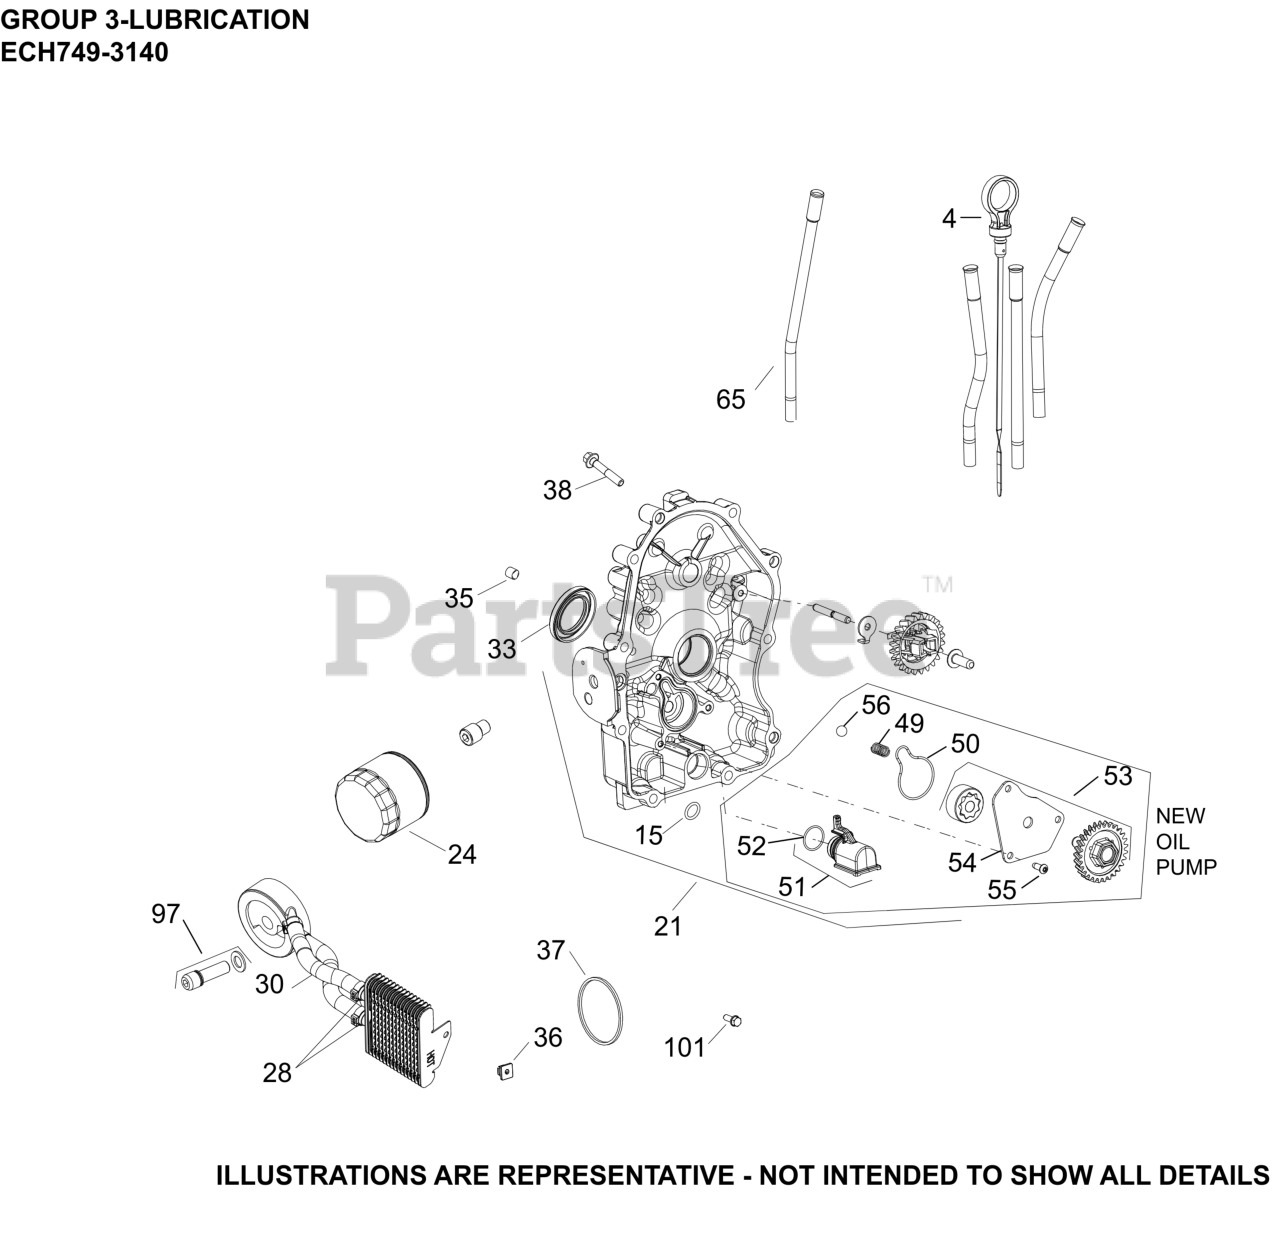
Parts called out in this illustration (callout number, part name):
21	CLOSURE PLATE ASSEMBLY (SERVICE)
24	OIL FILTER
28	CLAMP, HOSE LOW PROFILE
30	KIT, HOSE 140MM
35	PLUG, CTSK PIPE 1/8"
36	NUT, PLASTIC - BLACK
37	O-RING, OIL COOLER
38	SCREW, FLG M8X1.25X45
38	SCREW, HEX FLANGE
49	SPRING, COMPRESSION
50	SEAL, OIL PUMP COVER
51	PICK-UP ASSEMBLY, OIL
52	O-RING, OIL PICK-UP
53	PUMP ASSEMBLY, OIL
54	COVER, OIL PUMP
55	SCREW, BUTTON HEAD
56	PRESSURE RELIEF BALL
65	TUBE, DIPSTICK
97	KIT, OIL FILTER NIPPLE
101	SCREW, HEX HEAD
NI	ADAPTER,OIL FILTER (CV EFI)-(#DSC)
NI	COOLER,OIL&DIVERTER ASSY-USE 24 594 69-S
NI	KIT, OIL PRESSURE SWITCH + BOOT
